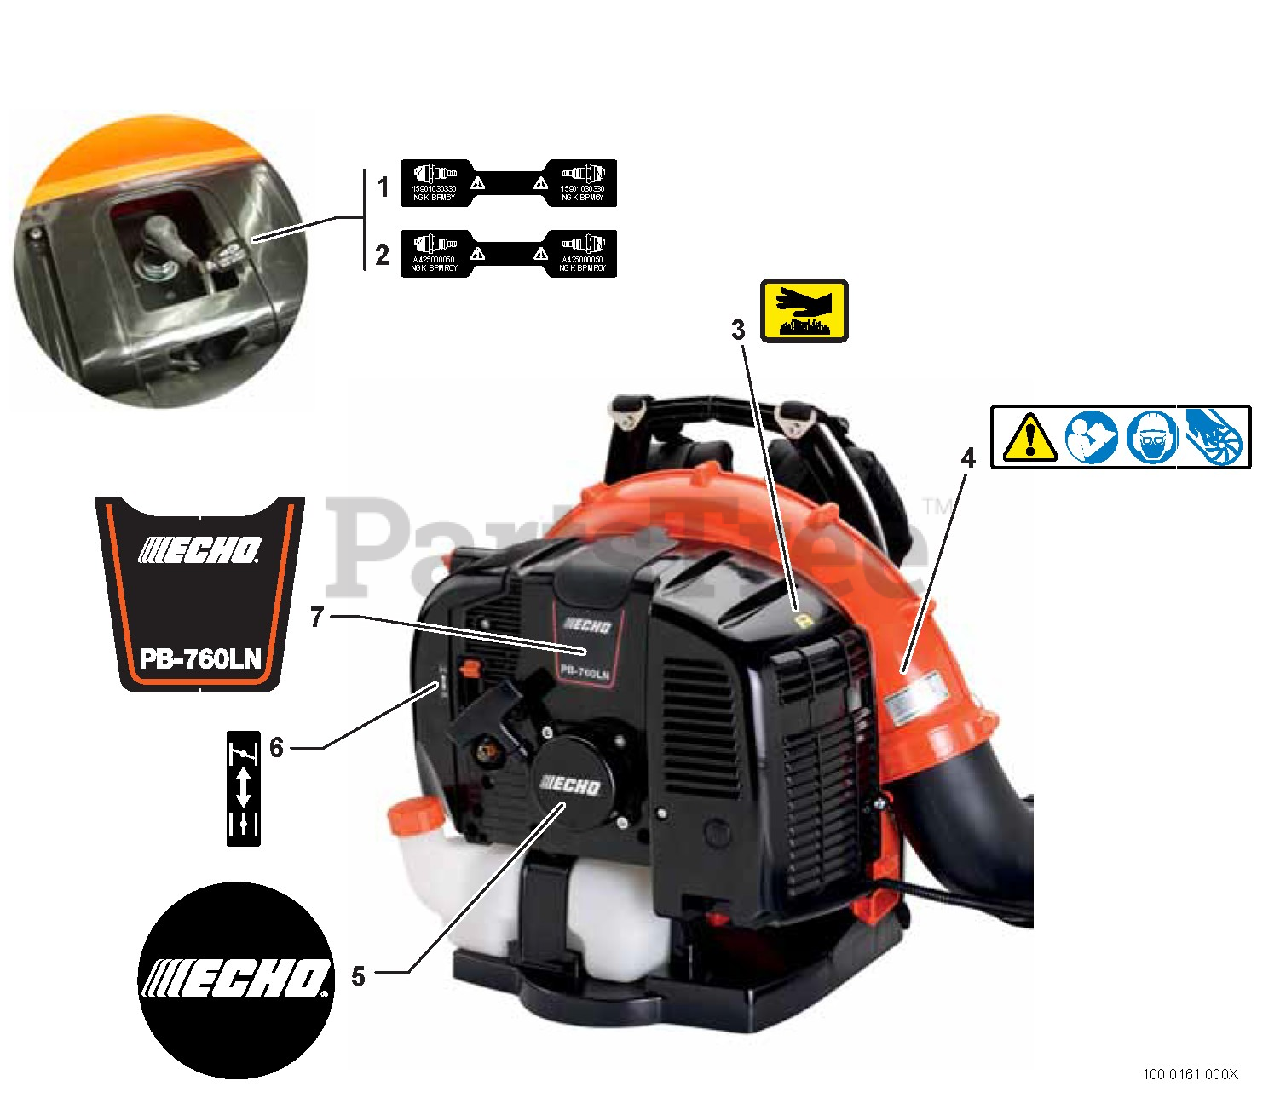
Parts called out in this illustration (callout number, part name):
1	LABEL - SPARK PLUG -- BPM-6Y
2	LABEL - SPARK PLUG -- BPMR-6Y
3	LABEL - HOT SURFACE
4	LABEL - CAUTION
5	LABEL - ECHO
6	LABEL - CHOKE
7	LABEL - MODEL PB-760LN
